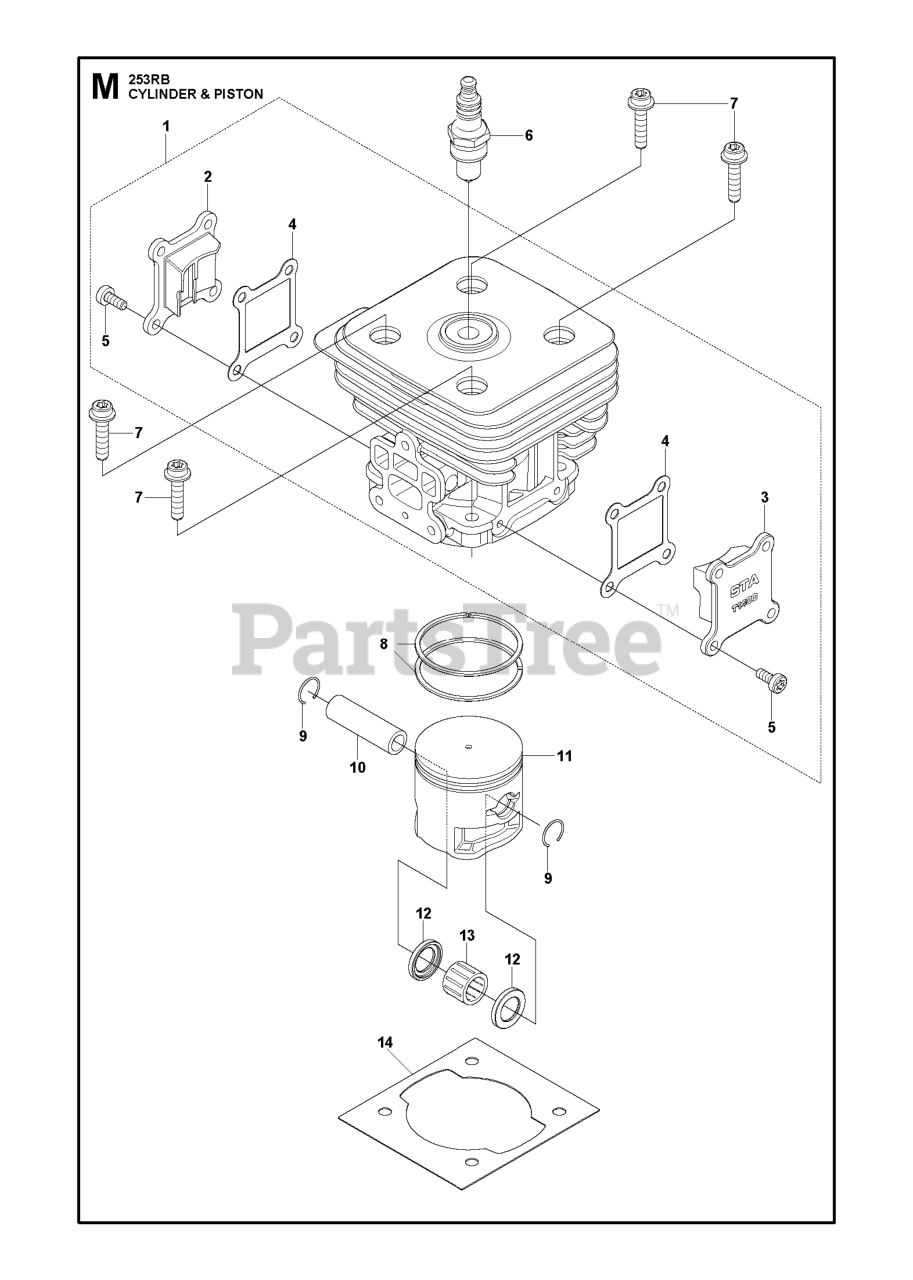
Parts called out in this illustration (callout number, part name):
4	GASKET, TR
6	PLUG CMR7H
8	RING
10	PISTON PIN
13	BEARING
